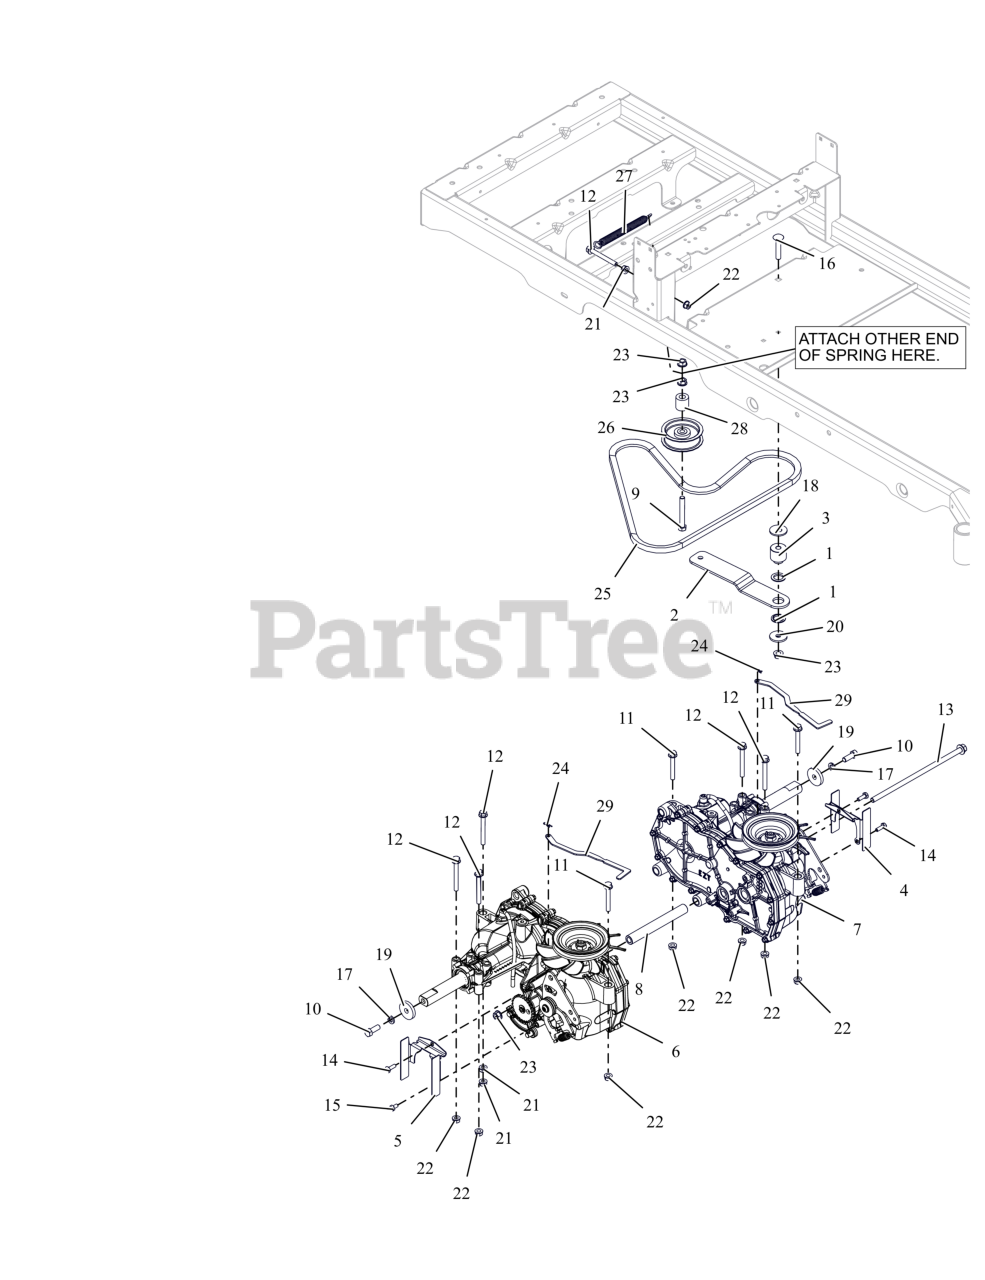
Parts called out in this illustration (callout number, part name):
1	BUSHING, IDLER ARM
2	IDLER ARM, GROUND DRIVE
3	SPACER, GROUND DRIVE IDLER
4	GUARD, PARKING BRAKE RH
5	GUARD, PARKING BRAKE LH
6	TRANSAXLE EZT D-SHFT SHORT
7	TRANSAXLE EZT D-SHFT SHORT
8	SPCR, TRANSAXLE .438 ID X .750 OD X 8.18
9	BLT, HEX .38-16X2.75 G5 ZCC
10	BLT, HEX .38-16X1.00 G8ZCCEP30
11	BLT,HEX-FLG .31-18X2.25 G5 ZCC
12	BLT,HEX-FLG .31-18X2.75 G5 ZCC
13	BLT, HEX-FLG 0.375-16X9.75 GR5 ZC120
14	@BLT-HEX .25-20X.75 GR5 YWZC
15	@BLT-HEX .25-20X.50 GR5 YWZC
16	BLT,RHSSN.375-16X2.00 G5 ZCC
17	WSHR,LK-REG .375X.094 ZCC
18	WSHR,FLT .563X1.375X.109 ZCC
19	WSHR, FLT .406X1.50X.245 ZCC
20	WSHR,FLT .406X1.375X.135 ZCC
21	NUT,SPNLK-FLG .31-18 G5 ZCC
22	NUT,LK-CTR-FLG .31-18 GF ZCC
23	NUT-LK-CTR-FLG .375-16 GF ZCC
24	PIN, HAIR #178 .06X.77 ZCC
25	V-BELT, HA-RAW EDGE
26	PULLEY, ENGINE CLUTCH 03608
27	SPRING, EXTENSION
28	BSHG-SLV .391X.688X.52 PM
29	BRKT, VALVE DUMP (BLACK)
